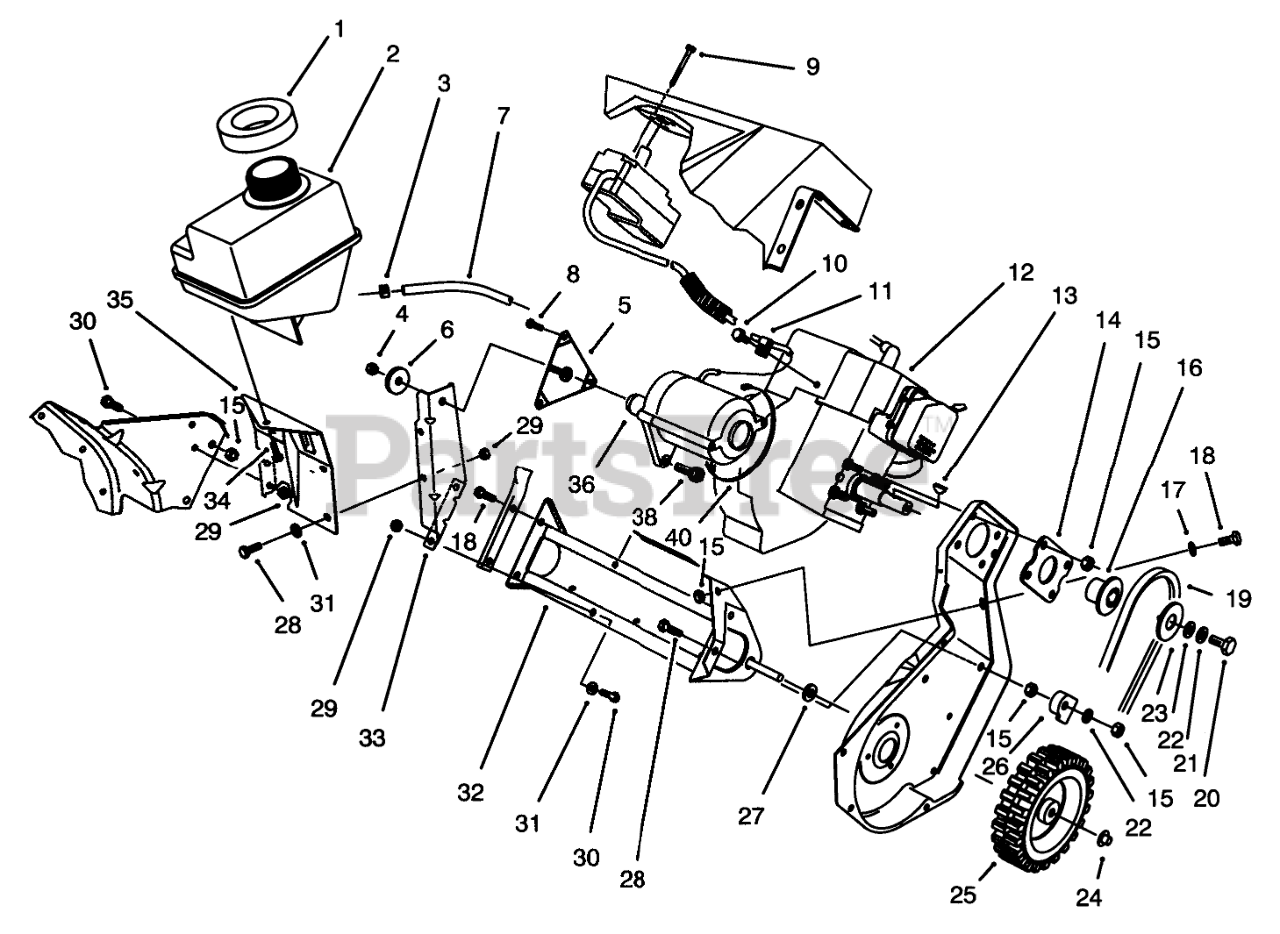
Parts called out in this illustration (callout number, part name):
1	SEAL-FOAM
2	Tank-Gas
3	Clamp
4	NUT-LOCK, NI
5	BRACKET AND STUD ASM
6	WASHER-SUPPORT, ENGINE
7	LINE-FUEL
8	SCREW X
9	SCREW-PLASTITE
10	SCREW-HWH
11	CLAMP
12	Engine Assy.
13	KEY-WOODRUFF
14	Plate Engine
15	NUT-LOCK, NI
16	Hub-HALF SHEAVE
17	WASHER-PLAIN
18	SCREW-HH
19	V-BELT
20	SCREW-HH
21	WASHER-BELLEVILLE
22	WASHER-FLAT
23	CAP-HALF SHEAVE
24	RETAINER-PUSH ON
25	WHEEL
26	GUIDE-CABLE
27	SPACER-PLASTIC
28	SCREW-HH
29	NUT-LOCK, NI
30	SCREW-HH
31	WASHER-FLAT
32	Frame Assembly
33	Support-Engine
34	SCREW-SHWH, THREAD FORMING
35	Bracket-Fuel Tank
36	Starter Switch Assembly
38	SCREW-HH, TORX
40	TIE-CABLE
